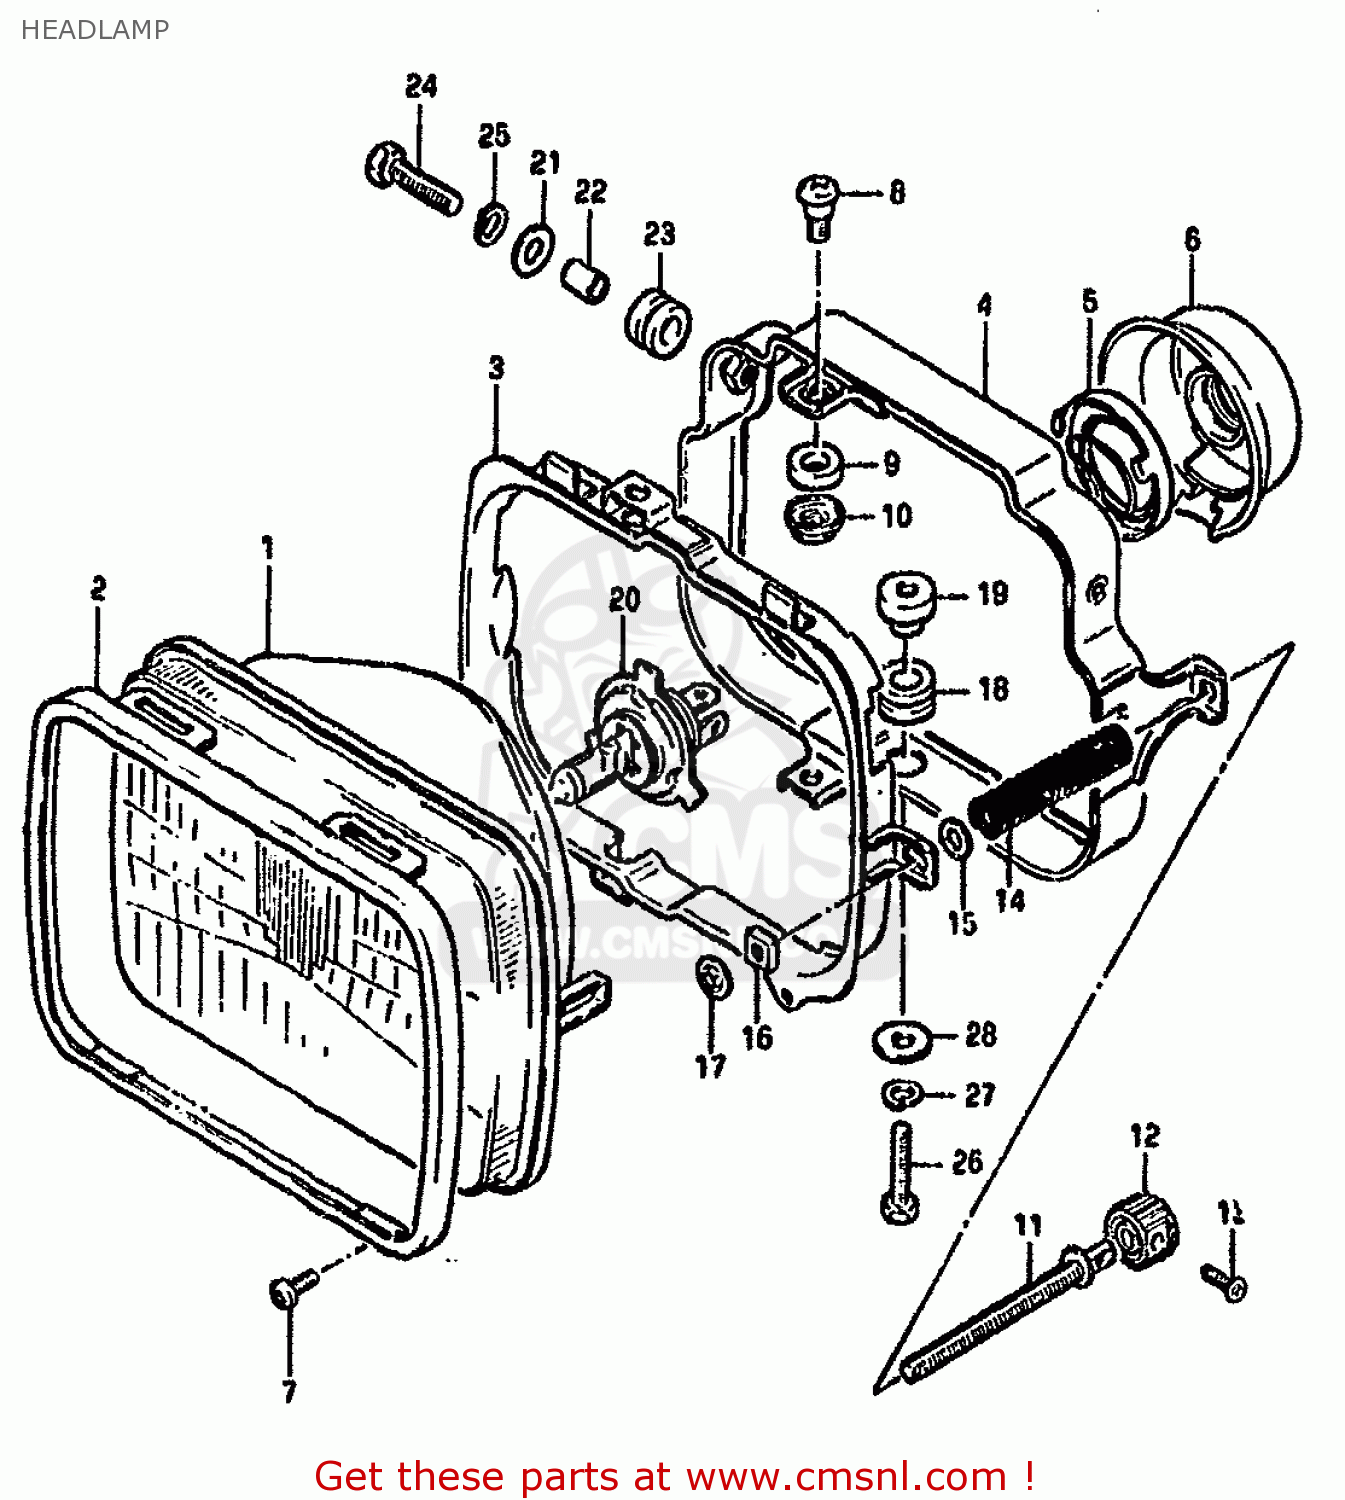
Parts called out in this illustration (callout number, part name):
1	LAMP UNIT
2	RETAINER
3	RING,MOUNTING
4	HOUSING
5	HOLDER, BULB
6	COVER,HEADLAMP SOCKET
7	SCREW
8	SCREW
9	SPACER
10	NUT,ADJUSTING
11	SCREW,ADJUSTING
12	KNOB,ADJUSTER
13	SCREW
14	SPRING
15	WASHER
16	NUT
17	NUT,HEADLAMP ADJUSTER
18	CUSHION
19	NUT
20	BULB(12V60/55W,H4)
21	WASHER
22	SPACER (6.1X8X9.5)
23	CUSHION
24	BOLT
25	LOCK WASHER
26	SCREW(6X20)
27	LOCK WASHER
28	WASHER
